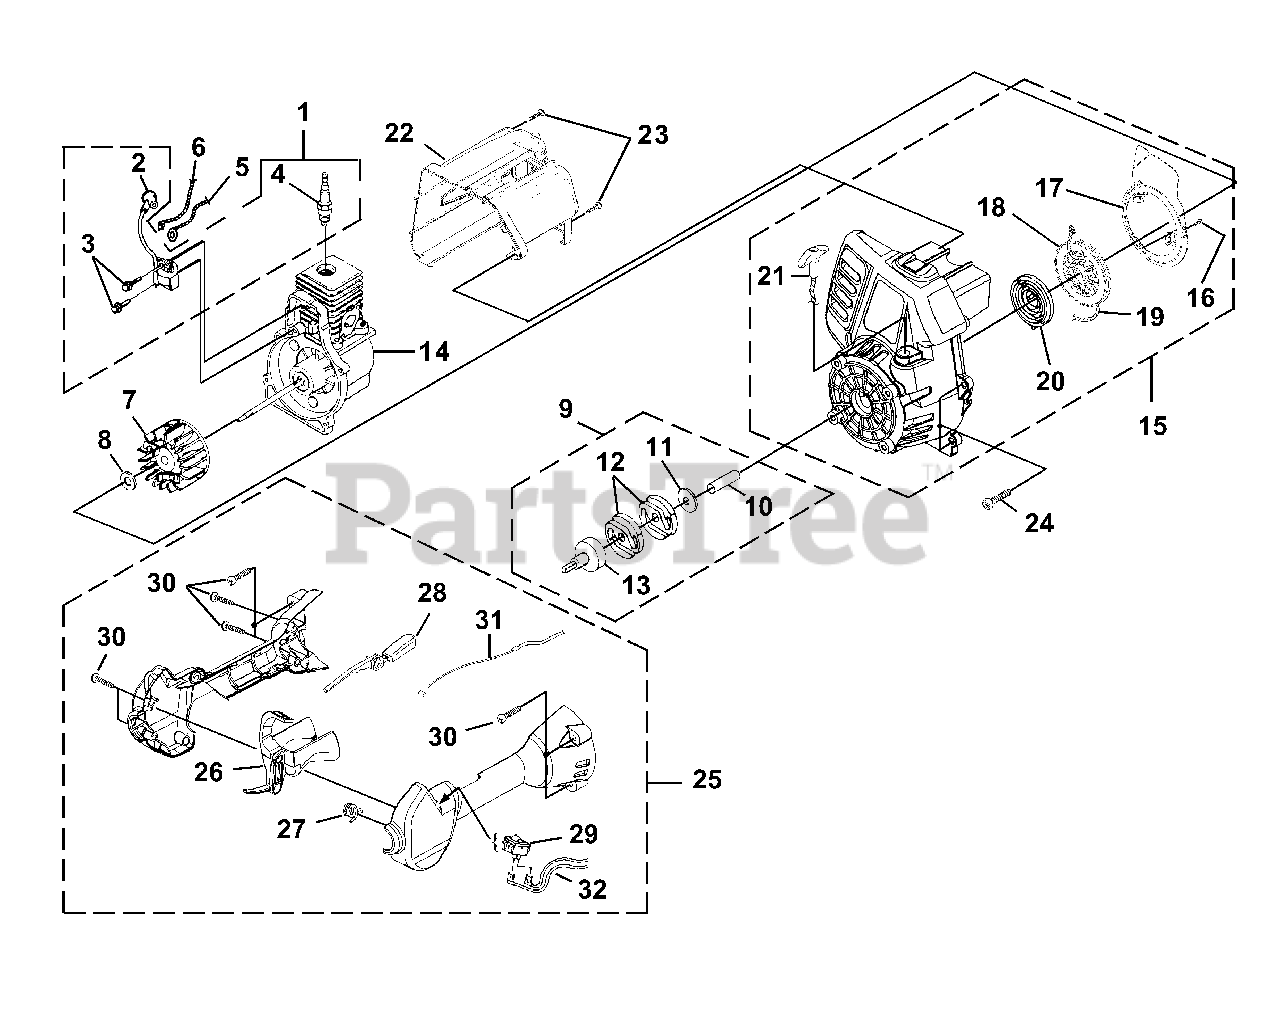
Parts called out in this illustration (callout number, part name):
1	IGNITION KIT
2	TERMINAL & COVER
3	SCREW-Taptite (8-32 X 1")
4	SPARK PLUG
5	LEAD-Electrical
6	LEAD-Electrical
7	ROTOR KIT
8	WASHER-Flat
9	CLUTCH AND DRUM KIT
10	SPACER
11	WASHER-Flat
12	CLUTCH
13	CONNECTOR AND DRUM
14	SHORT BLOCK
15	COMPLETE STARTER ASSEMBLY
16	SCREW-Thread Form (8-16 X 1/2")
17	BAFFLE-Air
18	PULLEY-Starter
19	ROPE-Starter (42")
20	SPRING & CONTAINER
21	GRIP-Starter (Yellow)
22	HOUSING-Rear Kit
23	SCREW-Plastite (10-14 X 3/4")
24	SCREW-Taptite (10-24 X 3/4")
25	CONTROL HANDLE ASSY.
26	TRIGGER-Throttle
27	SPRING
28	THROTTLE INTERLOCK
29	SWITCH
30	SCREW-Taptite (10-14 X 1")
31	CABLE-Throttle
32	LEAD-Electrical
